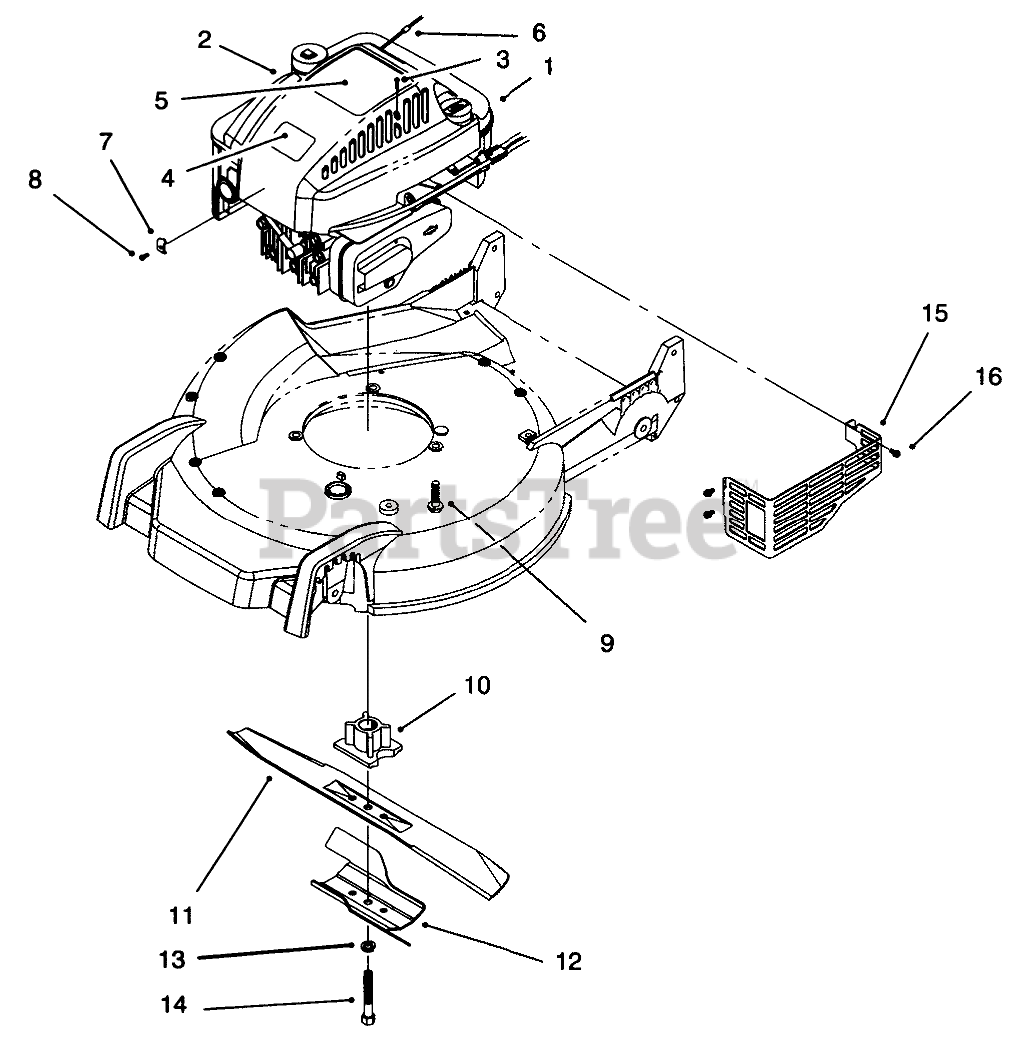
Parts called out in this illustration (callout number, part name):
2	SHROUD-ENGINE
3	SCREW-PPH
4	PLATE-LOGO
5	DECAL - RECOIL
6	STOP-ROPE
7	CLAMP-CASING
8	SCREW-CLAMP
9	SCREW-HWH
10	RETAINER - BLADE
11	Blade
12	Stiffener-Blade
13	WASHER-LOCK
14	SCREW-BLADE
15	SHIELD-MUFFLER
16	SCREW-HWH
